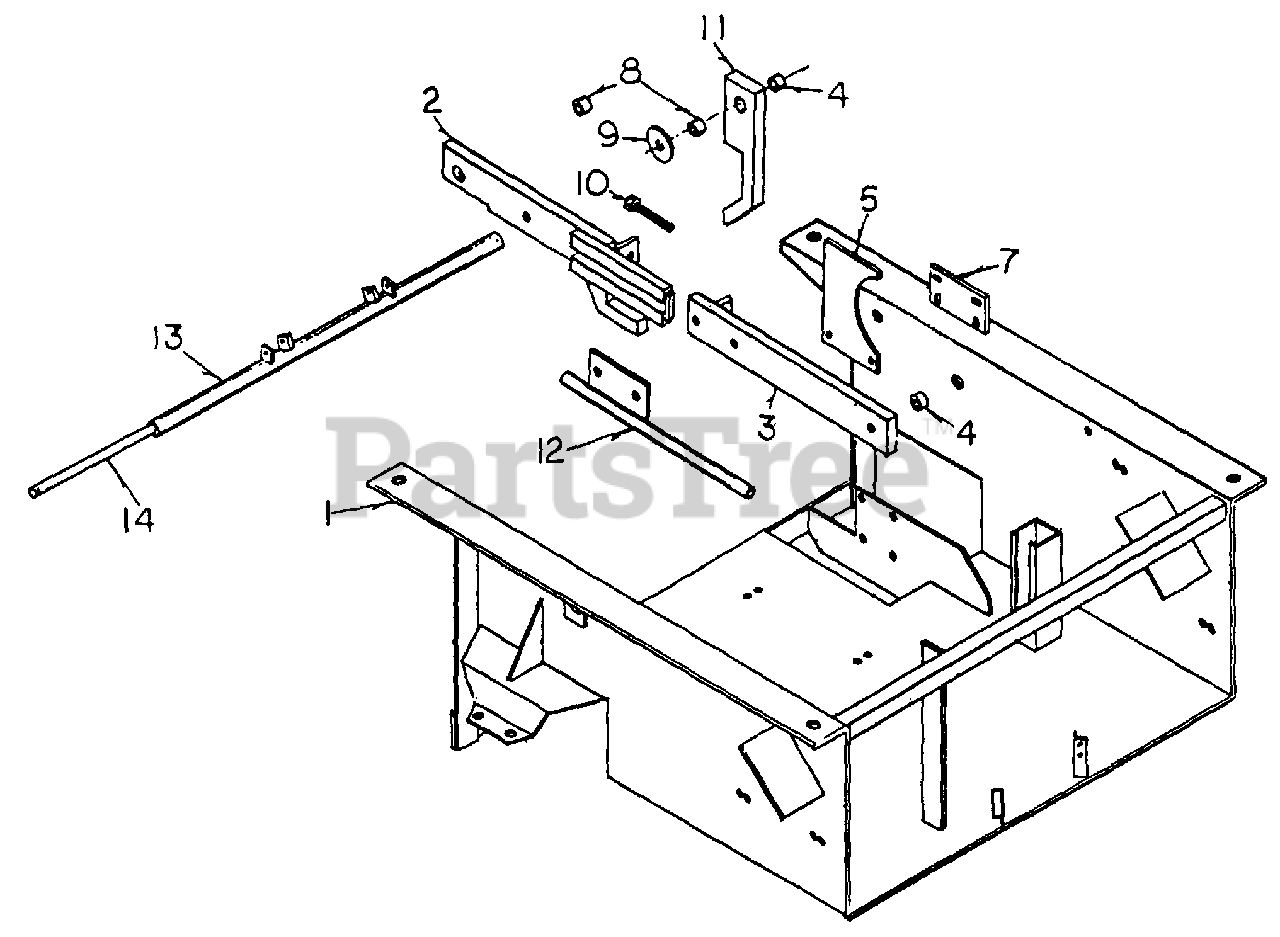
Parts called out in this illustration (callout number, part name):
1	Base
2	Deck Lift Arm, Front RH
3	Deck Lift Arm, Back
4	Bushing, Short
5	Belt Retainer
7	Belt Retainer Mount
8	Bushing, Long
10	Deck Belt Adjustment Bolt
11	Forward Nose Down Lock
14	Cross Bar Pin
